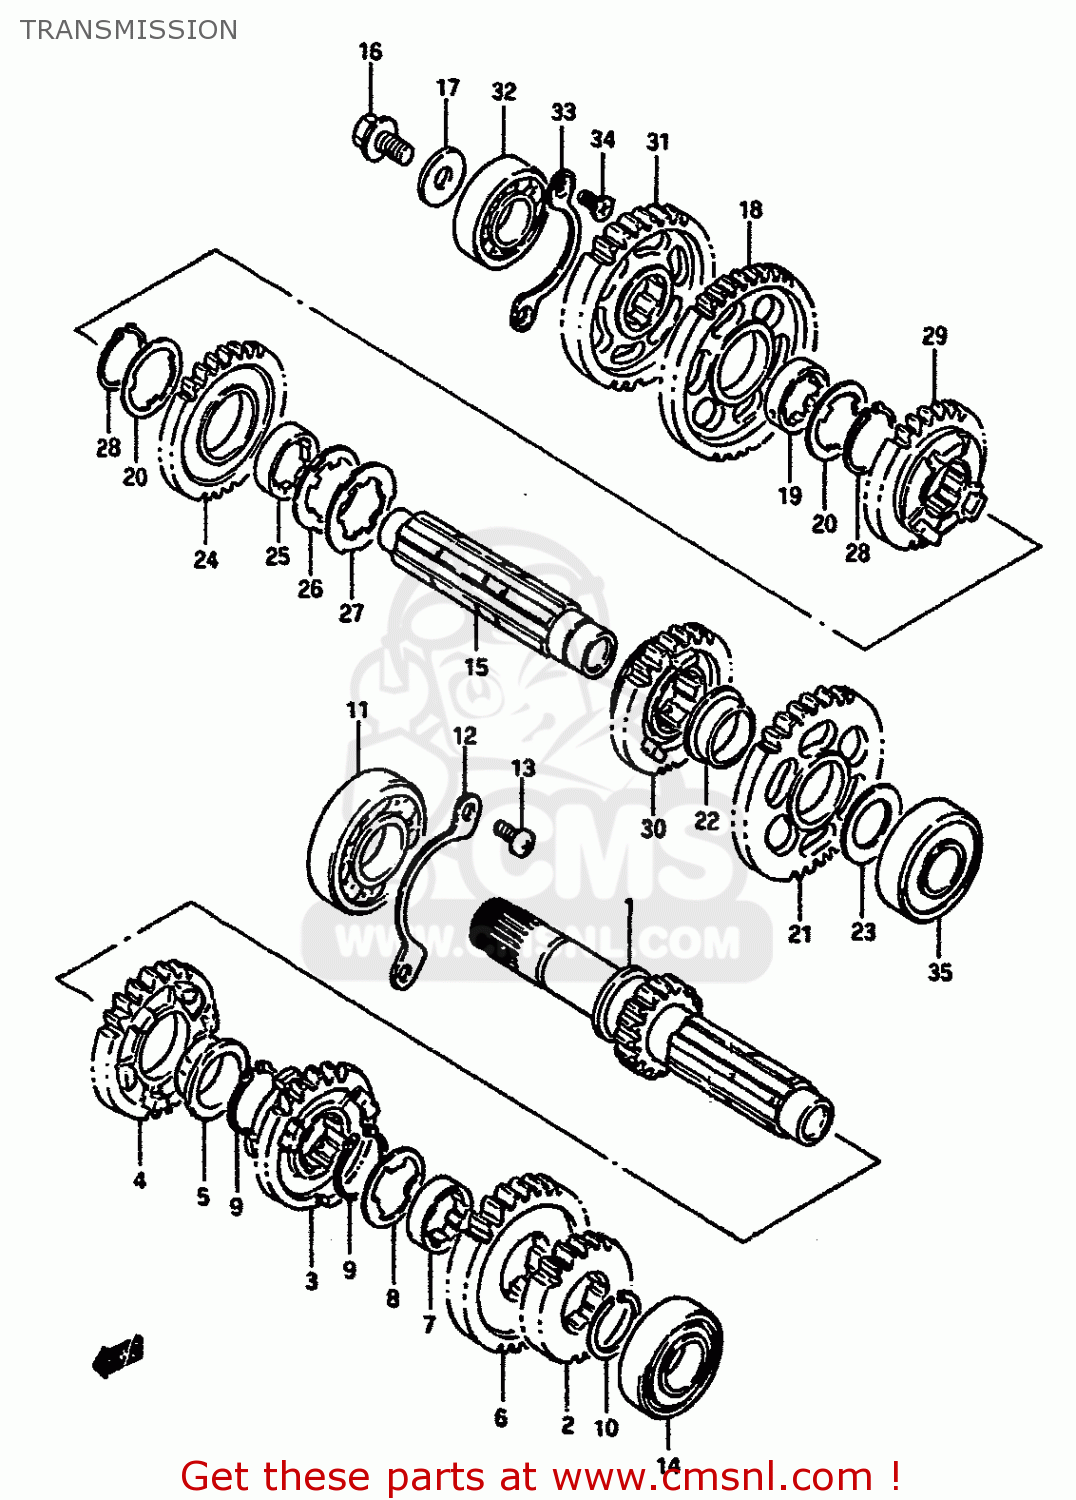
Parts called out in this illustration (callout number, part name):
1	COUNTER SHAFT
2	GEAR,2ND DRIVE(NT:19)
3	GEAR,THIRD DRIVE
4	GEAR,4TH DRIVE(NT:25)
5	BUSHING
6	GEAR,FIFTH DRIVE (NT:27)
7	BUSHING
8	WASHER,LOCK
9	RING,SNAP
10	CIRCLIP
11	BEARING(25X62X17)
12	RETAINER,CNTR SHAFT BEARING
13	SCREW
14	BEARING 20X47X14
15	SHAFT,DRIVE
16	NOZZLE,DRIVE SHAFT
17	WASHER
18	GEAR,FIRST DRIVEN (NT:32)
19	BUSH
20	WASHER,LOCK
21	GEAR,2ND DRIVEN(NT:31)
22	BUSH
23	WASHER
24	GEAR,3RD DRIVEN(NT:27)
25	BUSH
26	WASHER
27	WASHER,LOCK
28	CIRCLIP
29	GEAR,FOURTH DRIVEN
30	GEAR,FIFTH DRIVEN
31	GEAR,REDUCTION DRIVE(NT:30)
32	BEARING(20X52X15)
33	RETAINER,DRIVE SHAFT BEARING
34	SCREW
35	BEARING(20X52X15)
